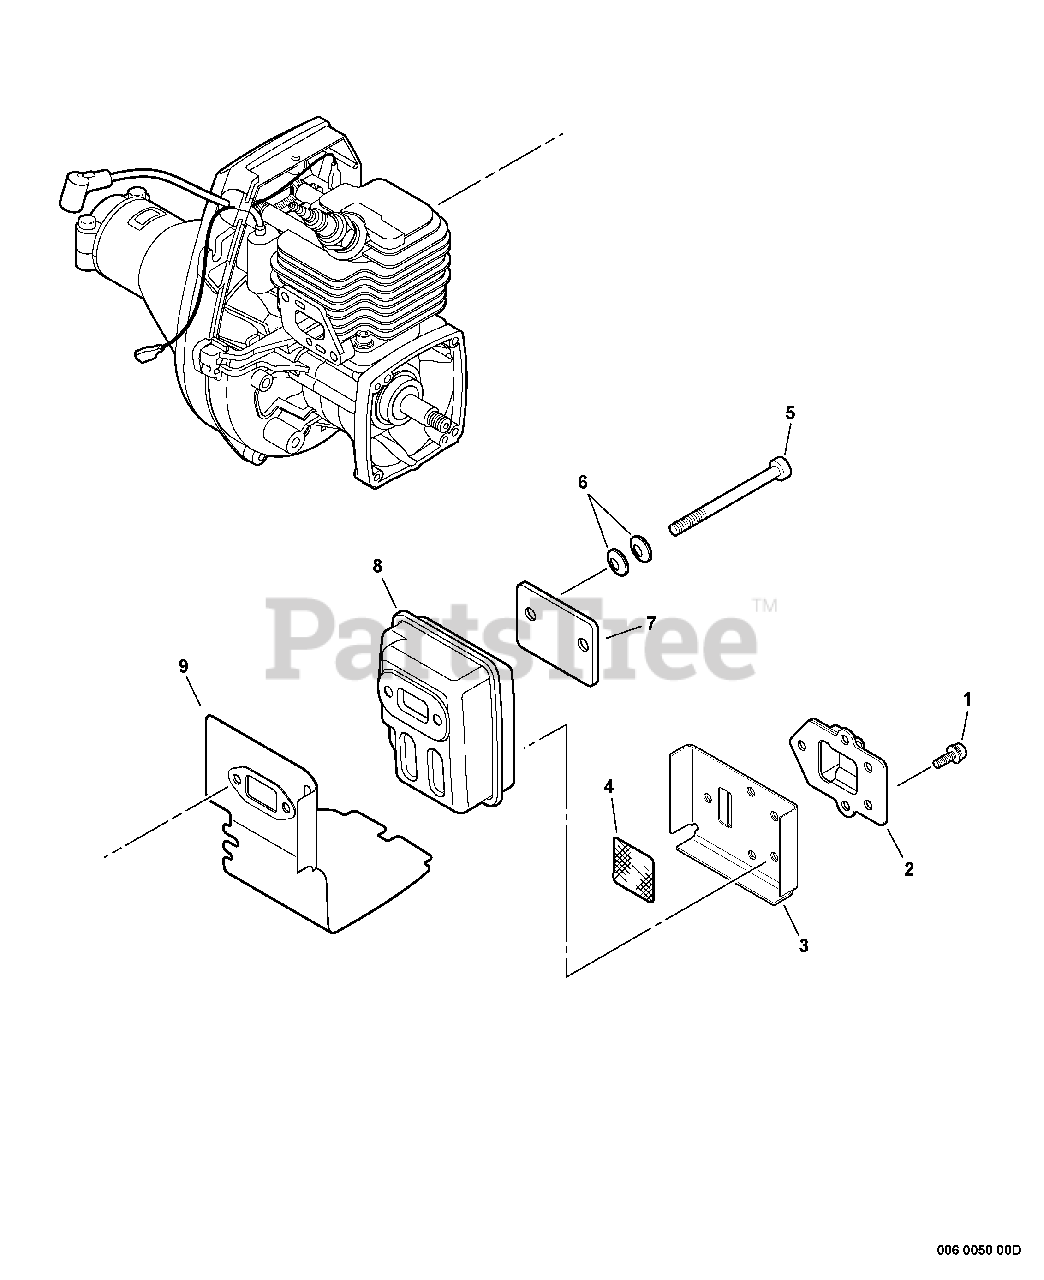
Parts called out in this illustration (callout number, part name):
1	SCREW - 4X10
2	GUIDE, EXHAUST
3	GASKET, EXHAUST
4	SCREEN, SPARK ARRESTOR
5	SCREW - 5X55
6	WASHER - CONICAL
8	MUFFLER
9	SHIELD, EXHAUST
